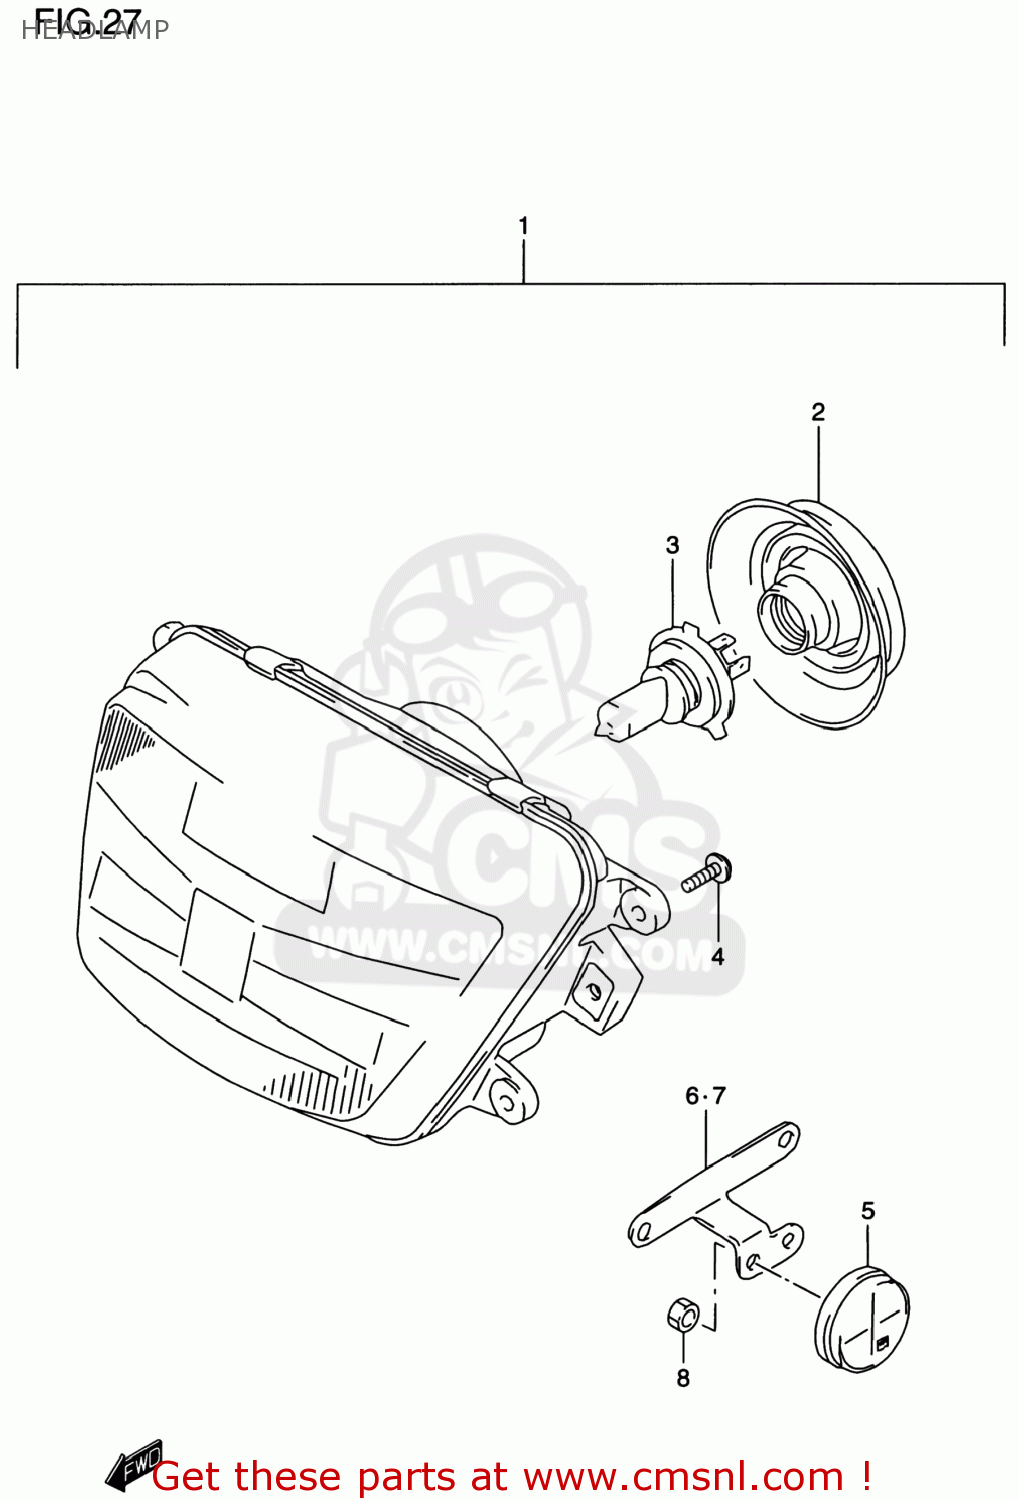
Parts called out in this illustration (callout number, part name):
1	HEADLAMP ASSY
2	COVER,SOCKET
3	BULB(12V60/55W,H4)
4	SCREW
5	REFLECTOR,REFLEX FR
6	BRACKET,FR SIDE REFLECTOR,R
7	BRACKET,FR SIDE REFLECTOR,L
8	NUT
